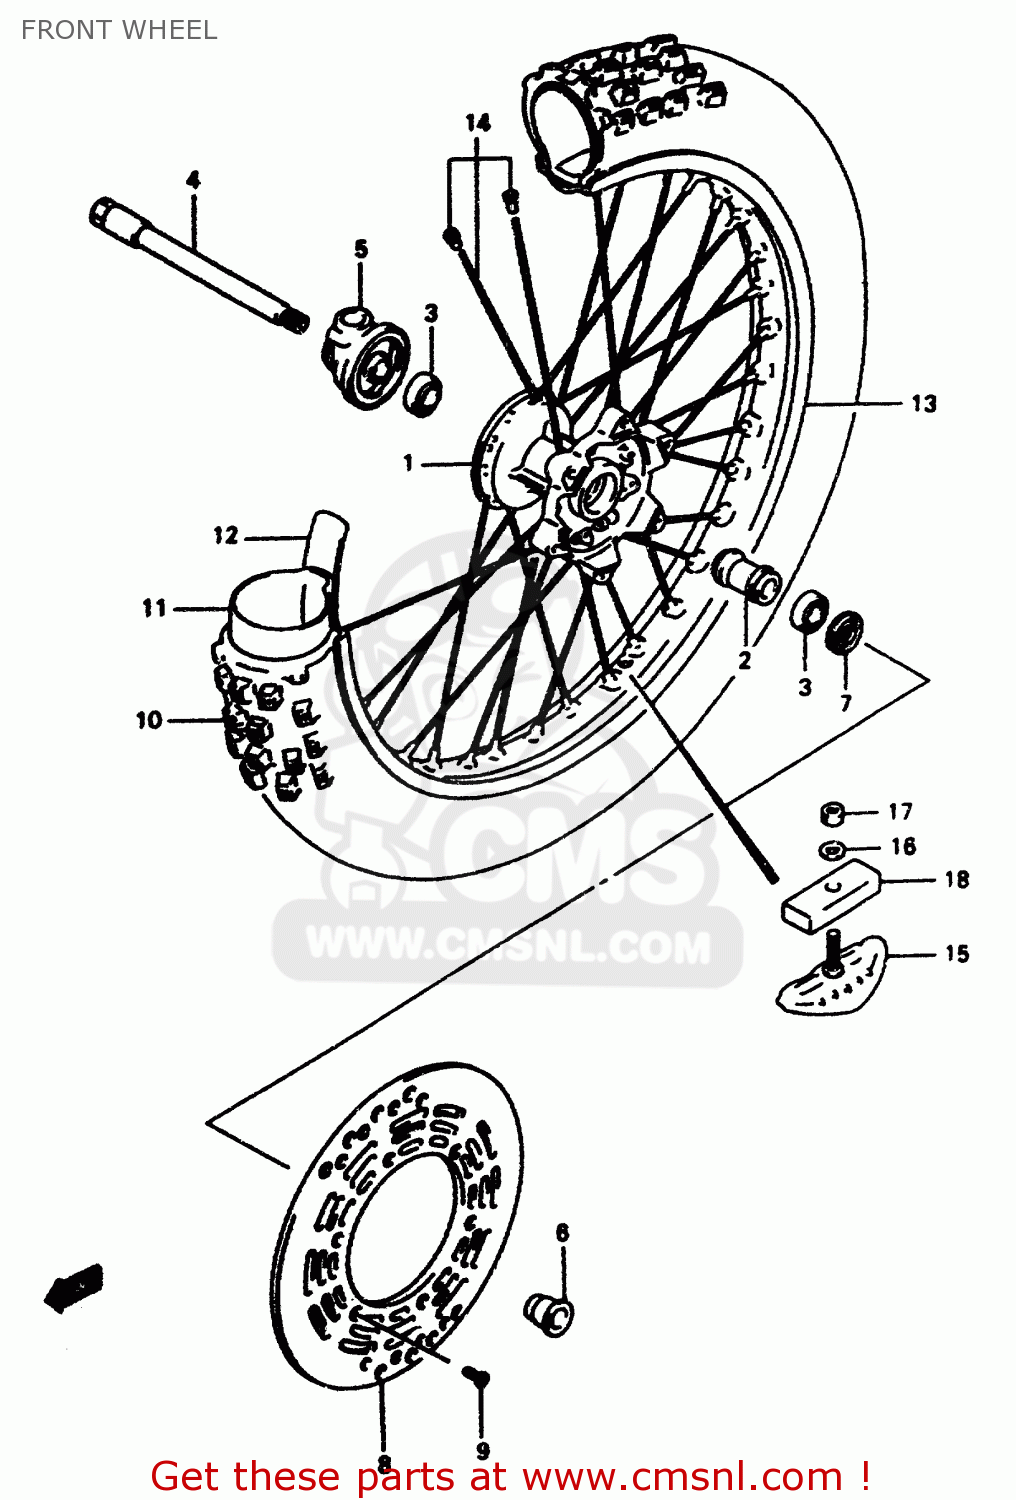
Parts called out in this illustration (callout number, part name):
1	HUB,FRONT WHEEL
2	SPACER,FR HUB BEARING
3	BEARING
4	AXLE,FR
5	BOX ASSY,SPEEDOMETER GEAR
6	SPACER,FR AXLE,L
7	SEAL,OIL(23X35X6)
8	DISC,FR BRAKE
9	SCREW
10	TIRE COMP,FRONT 80/100-21
11	TUBE
12	PROTECTOR,WHEEL INNER
13	RIM,FRONT WHEEL (1.60X2
14	SPOKE SET,FR WHEEL
15	STOPPER,BEAD
16	WASHER
17	NUT
18	CUSHION,BEAD STOPPER
